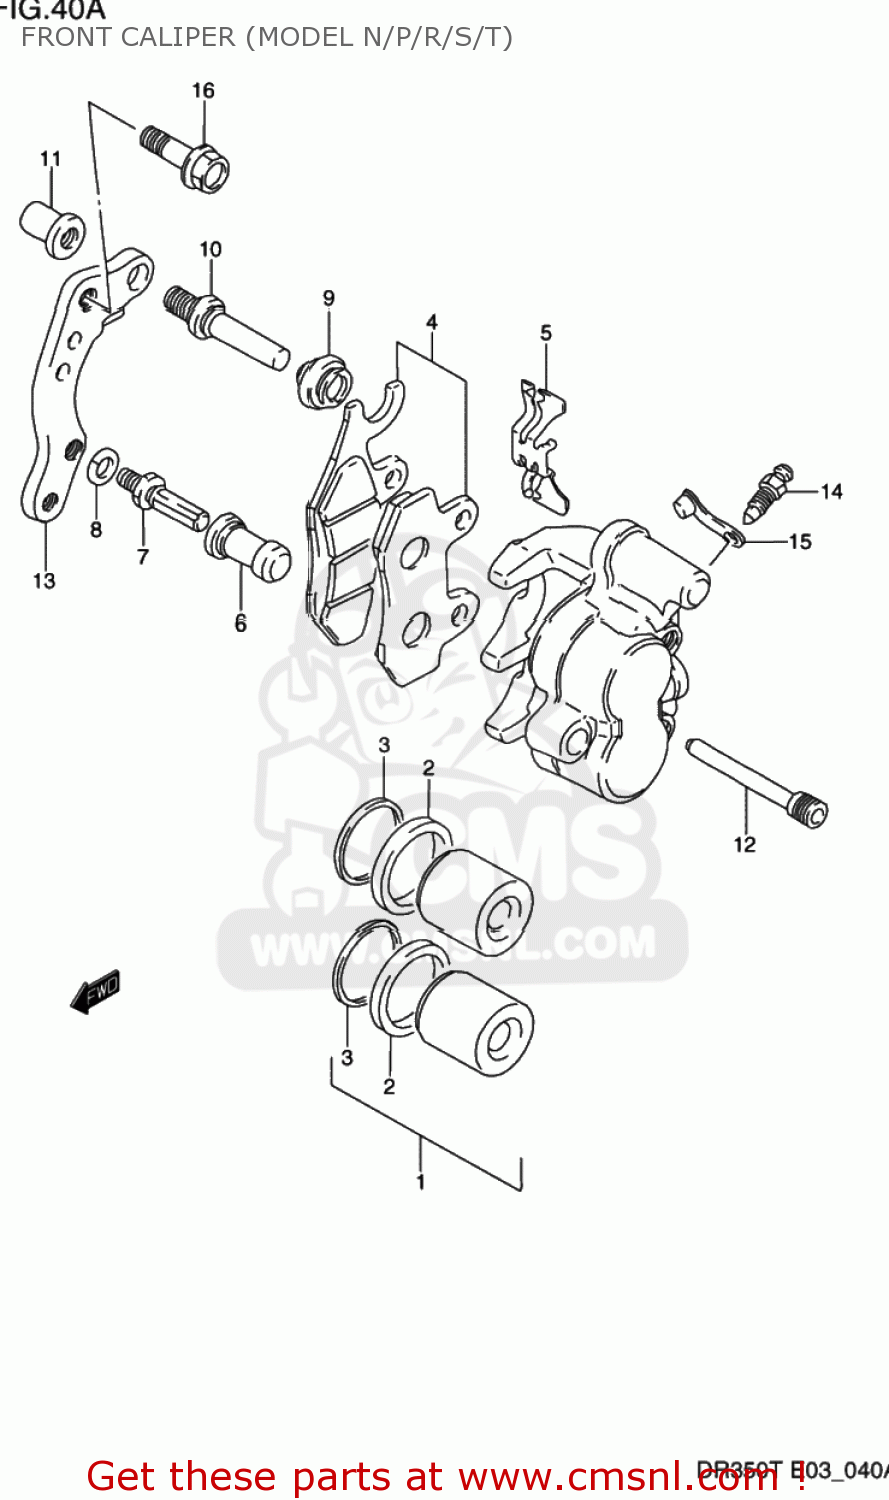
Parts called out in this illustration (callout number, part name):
1	PISTON SET
2	SEAL,PISTON
3	SEAL,DUST
4	PAD SET (NAS)
5	SPRING,PAD
6	BOOT
7	BOLT,PIN
8	WASHER,WAVE
9	BOOT
10	PIN,SLIDE
11	NUT
12	PIN,HOLDER
13	BRACKET
14	BLEEDER
15	CAP,BLEEDER
16	BOLT(8X24)
